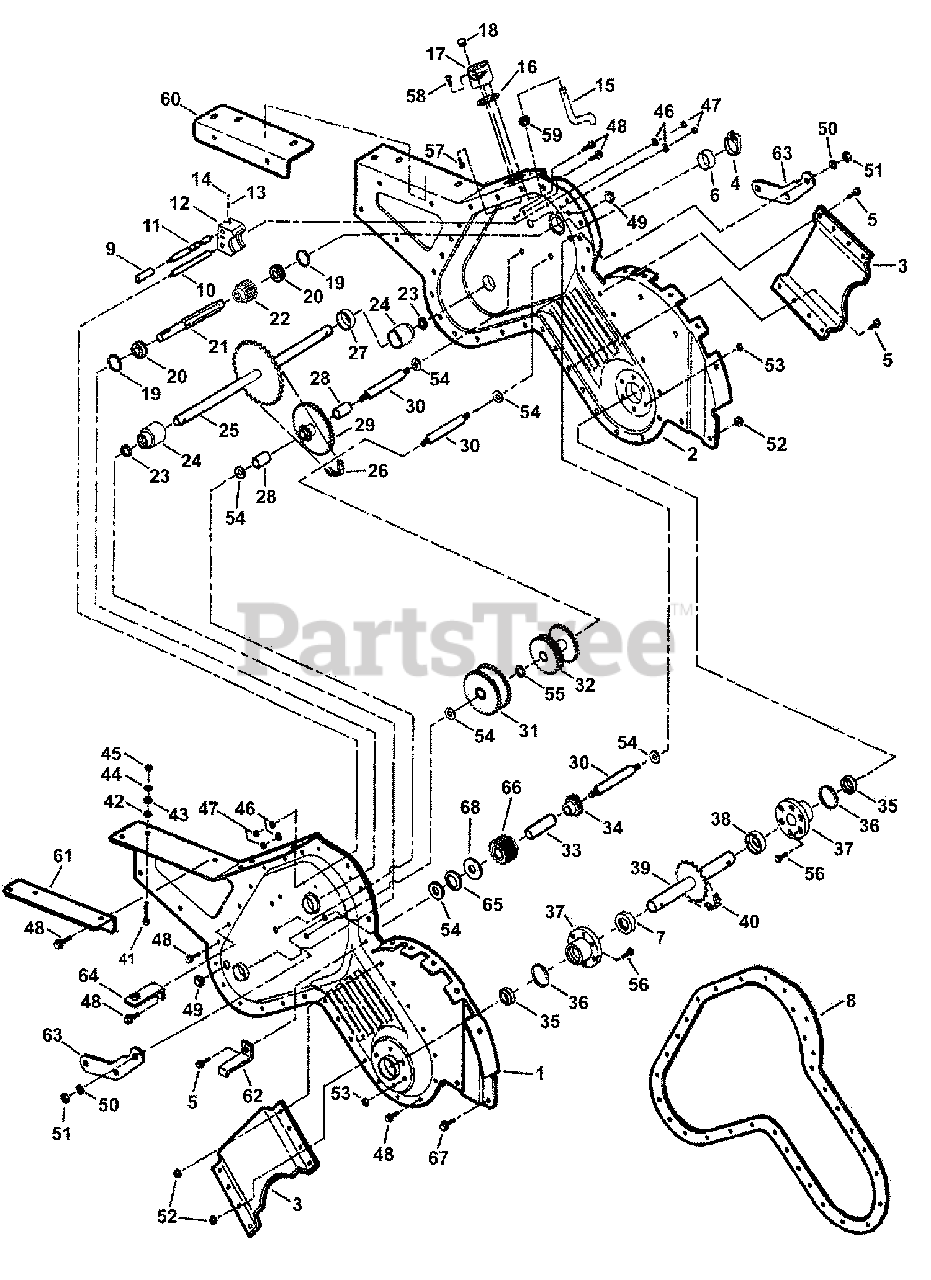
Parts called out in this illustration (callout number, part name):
1	CASE HALF, Left Hand
2	CASE HALF, Right Hand
3	REINFORCEMENT, Case
4	CLAMP, Speedy
5	BOLT, 5/16-18 x 1" Hex Flange Lock
6	SEAL, Cap
7	SPACER, Tine Shaft (Short)
8	GASKET, Main Case IR5003B Tiller
9	SPACER, Main Shaft (.47" long)
10	PIN, Guide
11	SHAFT, Main Detent (5 Position) ICFR
12	FORK, Primary Shaft
13	SPRING, Compression
14	BALL, Detent
15	CRANK, Shift
16	GASKET, Shift Arm Pivot
17	PIVOT, Shift Arm
18	PLUG, 1/2" Button
20	BEARING, .625 x 1.37 x .435
21	SHAFT, Input
22	PINION, Input ICFR
23	SEAL, Oil
24	BEARING, Axle
25	WELDMENT, Axle (#40/34T)
26	CHAIN, Traction #40
27	SPACER, Wheel Shaft (.686" Thick)
28	SPACER, 5/8 x 1.11"
29	GEAR & SPROCKET
30	SHAFT, Gear
31	* ASSY, F&R Tine Drive Gear #50, Spkt 10T Gear 34T
32	* ASSEMBLY, Wheel Drive Gear
33	SPACER, Reverse Idler (1.245" long)
34	* ASSEMBLY, Reverse Idler
35	SEAL, Oil
36	O-RING
37	BEARING, Tine Shaft
38	SPACER, Tine Shaft Long
39	WELDMENT, Tine Shaft (#50/18T)
40	CHAIN, Tine (Endless Roller) #50
41	SCREW, 5/16-24 x 1-3/4" Hex Head Cap GR5
42	RETAINER, 5/16" Bolt (Black)
43	WASHER, 5/16" Flat
44	WASHER, 5/16" Split Lock
45	NUT, 5/16-24 Hex
46	WASHER, 1/4" Internal Tooth Lock
47	NUT, 1/4-20 Hex
48	SCREW, 5/16-18 x 5/8" Hex Washer Self-Tap
49	PLUG
50	WASHER, 7/16" Internal Tooth Lock
51	NUT, 7/16-20 Hex
52	NUT, 5/16-18 Hex Flange Lock
53	NUT, 1/4-20 Hex Flange Lock
54	SHIM-WASHER
55	SHIM WASHER, 5/8"
56	SCREW, 1/4-20 x 5/8" Hex Head Cap GR5
57	SCREW, 1/4-20 x 1/2" Hex Washer Self-Tap
58	SCREW, 1/4-20 x 3/4" Hex Washer Self-Tap
59	O-RING, #012
60	REINFORCEMENT, R.H. Frame
61	REINFORCEMENT, L.H. Frame
62	BRACE, Belt Cover
63	SIDE PLATE
64	BRACKET, Belt Cover- IRT
65	WASHER, Shim
66	* ASSY, Gear 16T (Incl. two 15339 DX Bearings)
67	BOLT, 5/16-18 x 5/8" Hex Flange Lock
68	WASHER, Shim .63 x 1.24 x .05
